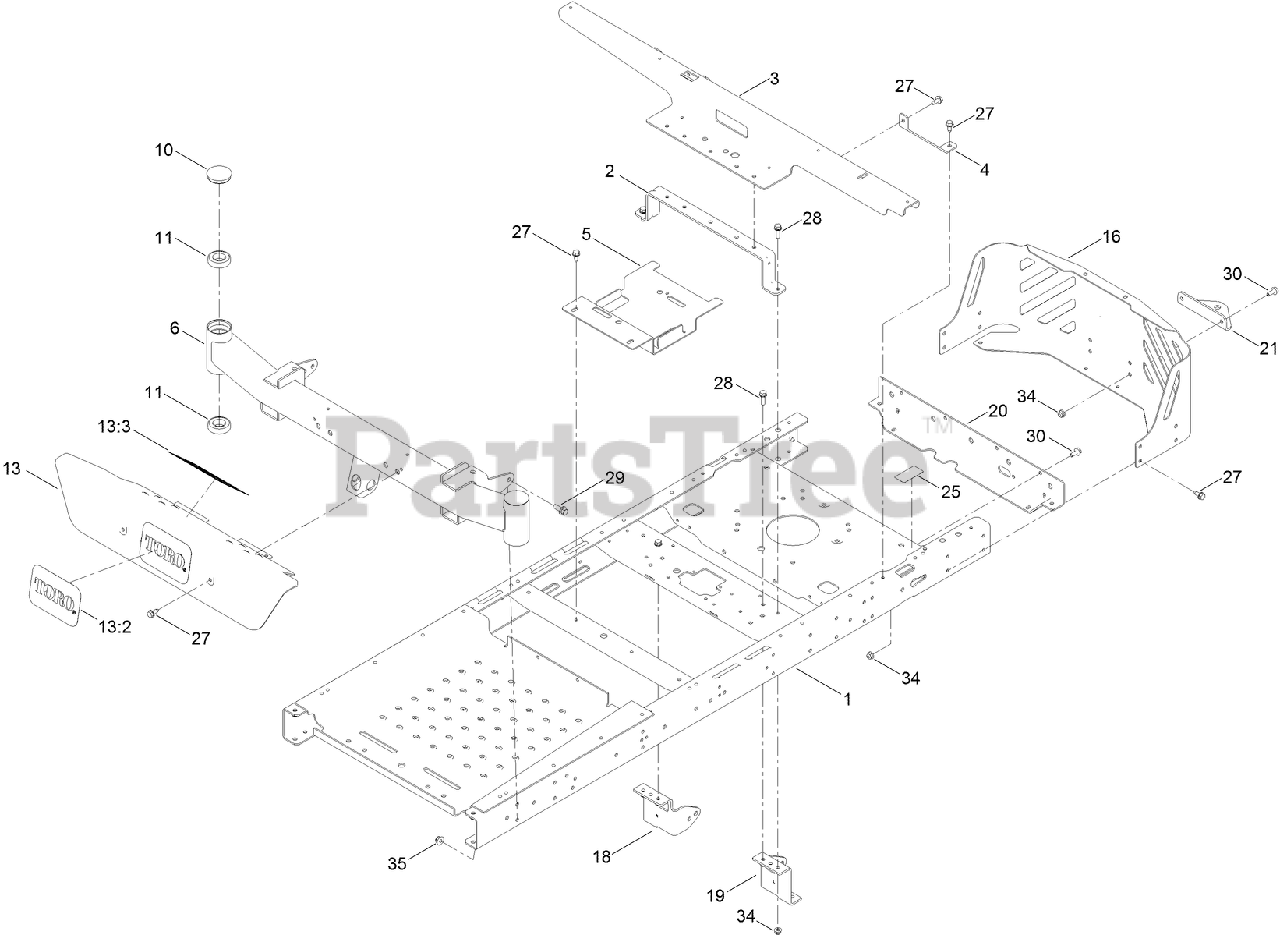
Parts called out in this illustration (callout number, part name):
1	RIVETED FRAME ASM (WIDE LEVER)
2	BRACE-SEAT, REAR (WIDE)
3	SUPPORT-POD, WIDE
4	SUPPORT-TANK, REAR
5	BRACKET-BATTERY
6	AXLE-WIDE
10	CAP-GREASE
11	BEARING-BALL
13	FOOTREST ASM
13:2	DECAL
13:3	DECAL-DANGER
16	GUARD-ENGINE, WIDE
18	MOUNT-HYDRO, FRONT (RIGHT)
19	MOUNT-HYDRO, FRONT (LEFT)
20	CROSSMEMBER-REAR, WIDE
21	BRACKET-HITCH
25	DECAL-BYPASS
27	SCREW-HWHTF
28	SCREW-HHF
29	SCREW-HHF
30	SCREW-HHF
34	NUT-HF, NI
35	NUT-HF, NI
